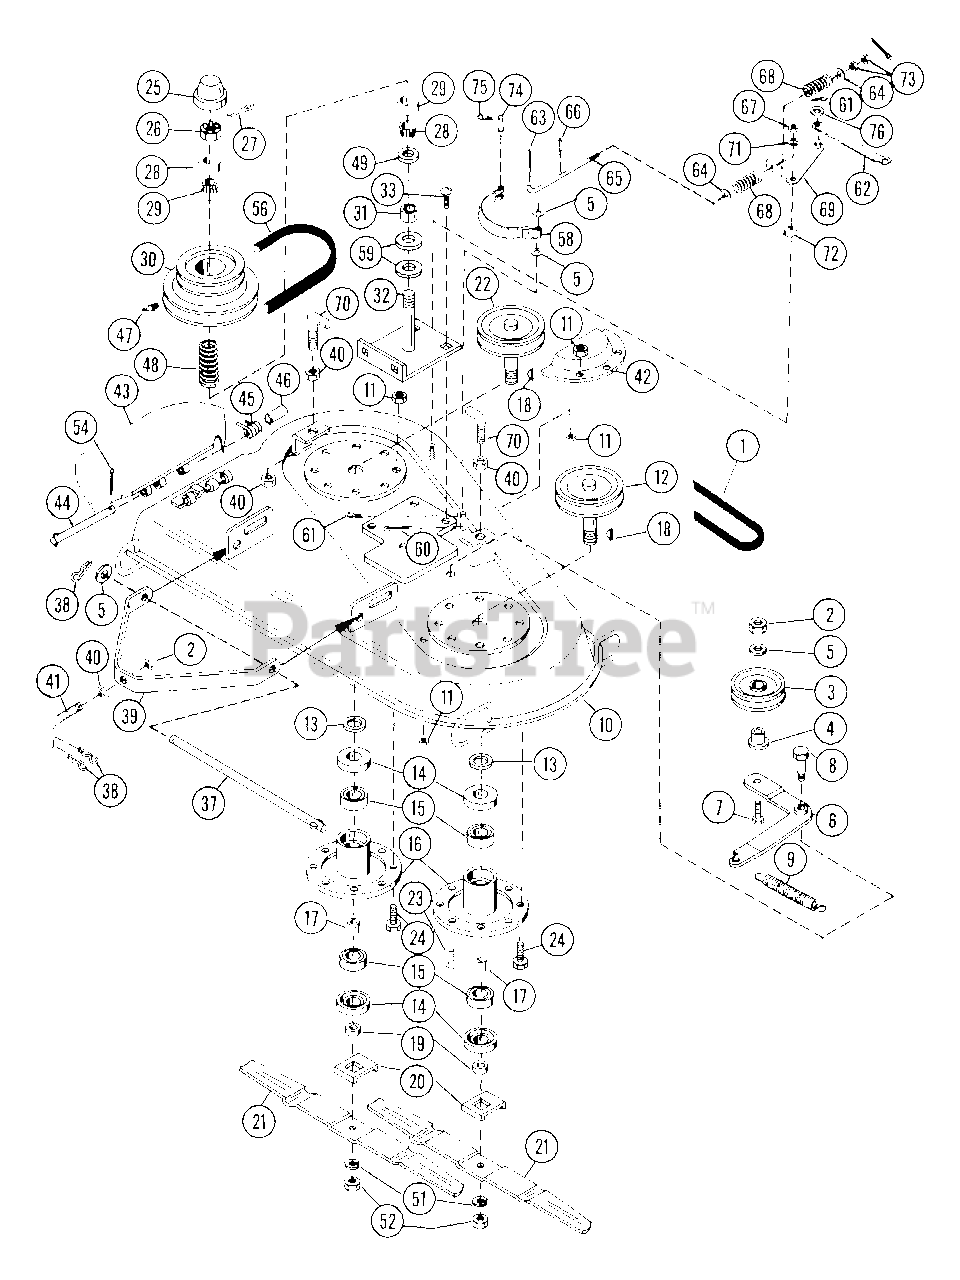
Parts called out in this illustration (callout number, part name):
1	V-BELT, 4L-RAW EDGE
2	NUT-LK-CTR .50-13
3	IDLER-FLAT 2.75X.62
4	BSHG-FLG .500X.625X.500X.750
5	WSHR-FL-STL .505X.880X.072 PL
7	BLT-HEX .50-13X1.25 PL GR2
8	SHOULDER BOLT
9	SG-TENS .091X.73X5.28 WLD 30
10	38 INCH MOWER PAN W/DECALS
11	NUT-LK-CTR .375-16 GR A PL
13	WSHR-FL-STL .755X1.250X.125
14	BEARING SLINGER
15	BRG-BALL .750X1.781X.61
16	SPINDLE HOUSING
17	SPACER .753X1.000X1.140
18	KEY-WDRF .188X.75X.313 SAE 9
19	RETAINER HUB
20	BLADE TRAY
21	MOWER BLADE
22	SHEAVE
23	BLT-HEX .38-16X1.00 PL
24	BLT-HEX .38-16X.75 PL GR2
25	CAP, GREASE
26	NUT-JAM SL .75-20 PL
27	PIN-COTR .12 X 1.25 PL
28	BRG-CONE .750X.61
29	BRG-CUP 1.781X.475
30	SHEAVE 38 IN PAN
31	SPACER .753X1.000X.625
33	BLT-RDHDSQNK .38-16X.75 SHT PL
37	TOW PIN
38	PIN-HAIR INT .09X.188 PL
39	MOWER STRAP
40	NUT-JAM .50-13 PL
42	COVER
43	CHUTE DEFLECTOR UNIT
44	CLEVIS PIN
45	SG-TORS .095X.50X 1.0
46	BSHG-SLV .334 X .502 X 1.437
47	SPIN DRIVE ZERK FITTING
48	SG-COMP .091X.950X2.062
49	SEAL .750X1.690X.153
51	WSHR-LK .750X.188 MED PL
52	NUT-JAM .75-10 PL
54	PIN-COTR .09X.75 PL
56	V-BELT, 4L-RAW EDGE
58	BRAKE BAND
59	WSHR-FL-STL .755X1.375X.062 PL
60	PIN-COTR .09X1.0 PL
61	PIN-HAIR INT .08X.38X1.42 YWZC
62	LINK
63	PIN-COTR .06X.50
64	WSHR-FL-STL .323X.625X.062 PL
65	BRAKE ROD
66	PIN-ROLL .125X.75
67	NUT-HEX .312-18
68	SG-COMP .057X.47X1.25
69	BRAKE LEVER
70	HANGER HOOK
71	WSHR-LK .312X.097 PL HVY
72	SPACER -FLANGED .325X.498X.318
73	NUT-JAM .312-18 PL
74	CLEVIS PIN
75	PIN-HAIR INT.06X.25X1.12
76	WSHR-FL-STL.406X.812X.065PL
